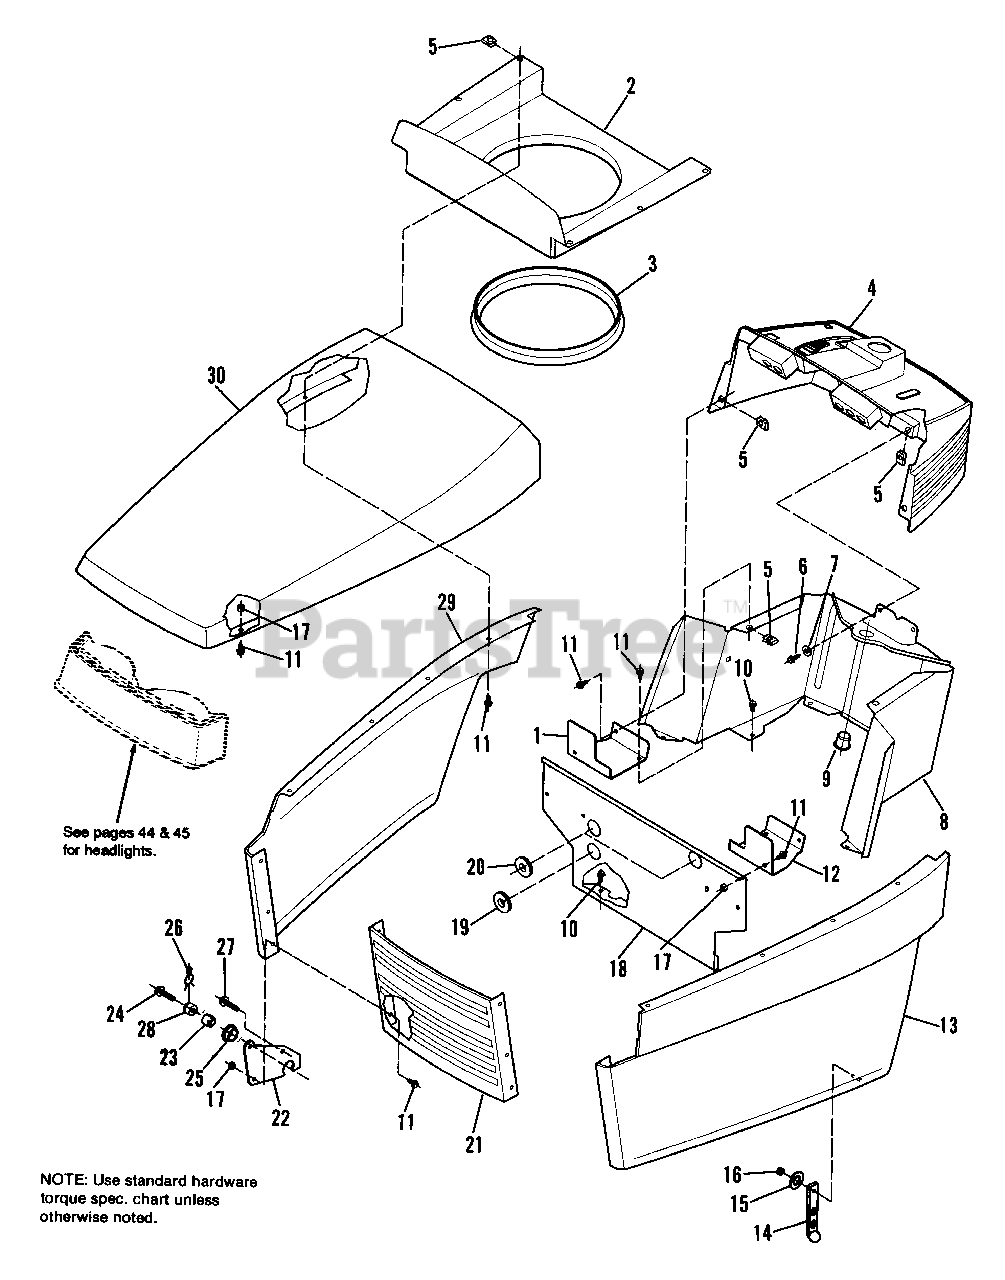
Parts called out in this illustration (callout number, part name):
1	SUPPORT, Bulkhead, R.H.
3	MOLDING, Air Duct
4	DASH ASSY. (Hydro Units only)
4	DASH ASSY. (Gear Units only)
5	PAL NUT, 1/4-20
6	SCREW, Cap Whizlock, 1/4-20 x 3/4 (Hydro Units Only)
7	WASHER, Plain, 1/4
8	DASH, Lower
9	BUSHING, Nylon
10	SCREW, Taptite, 1/4-20 x 1/2
11	CAPSCREW, Whizlock, 1/4-20 x 5/8 (Qty. 20 on Gear Units)
12	SUPPORT, Bulkhead, L.H.
13	SIDE PANEL ASSY., L.H.
14	STRAP, Hood
15	WASHER, Special
16	NUT, Hex Lock, Nylon #10-24
17	NUT, Hex Nylon Lock, 1/4-20
18	BULKHEAD
19	GROMMET, Wire Harness
20	GROMMETS, Bulkhead
21	GRILLE
22	HINGE, Hood
24	SCREW, Taptite, 5/16-18 x 1
25	SPACER, Hood
26	CLIP, Hairpin
27	SCREW, Taptite, 5/16-18 x 5/8
28	PIVOT, Hood
29	SIDE PANEL ASSY., R.H.
30	HOOD
